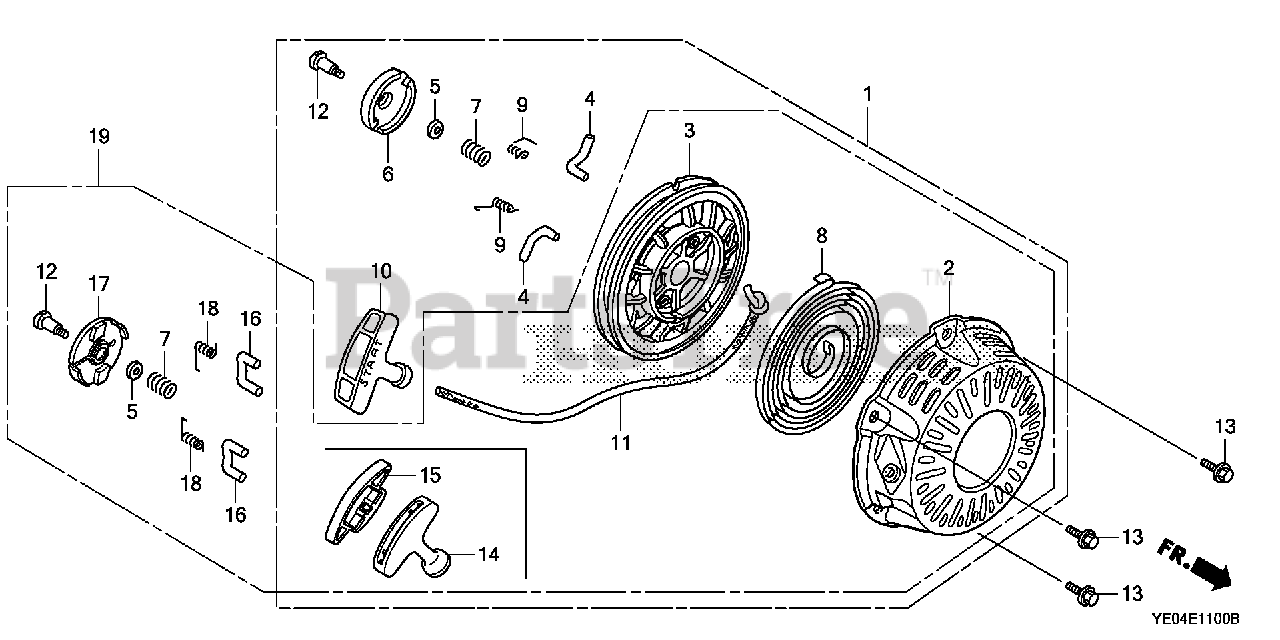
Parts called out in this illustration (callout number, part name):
1	STARTER ASSY., RECOIL *R280* (POWER RED)
2	CASE, RECOIL STARTER *R280* (POWER RED)
3	REEL, RECOIL STARTER (BLACK)
3	REEL, RECOIL STARTER
4	RATCHET, STARTER
5	PLATE, FRICTION
6	GUIDE, RATCHET
7	SPRING, FRICTION
8	SPRING, RECOIL STARTER
9	SPRING, RETURN
10	KNOB, RECOIL SRARTER
11	ROPE, RECOIL STARTER
12	SCREW, SETTING
13	BOLT, FLANGE (6X10)
